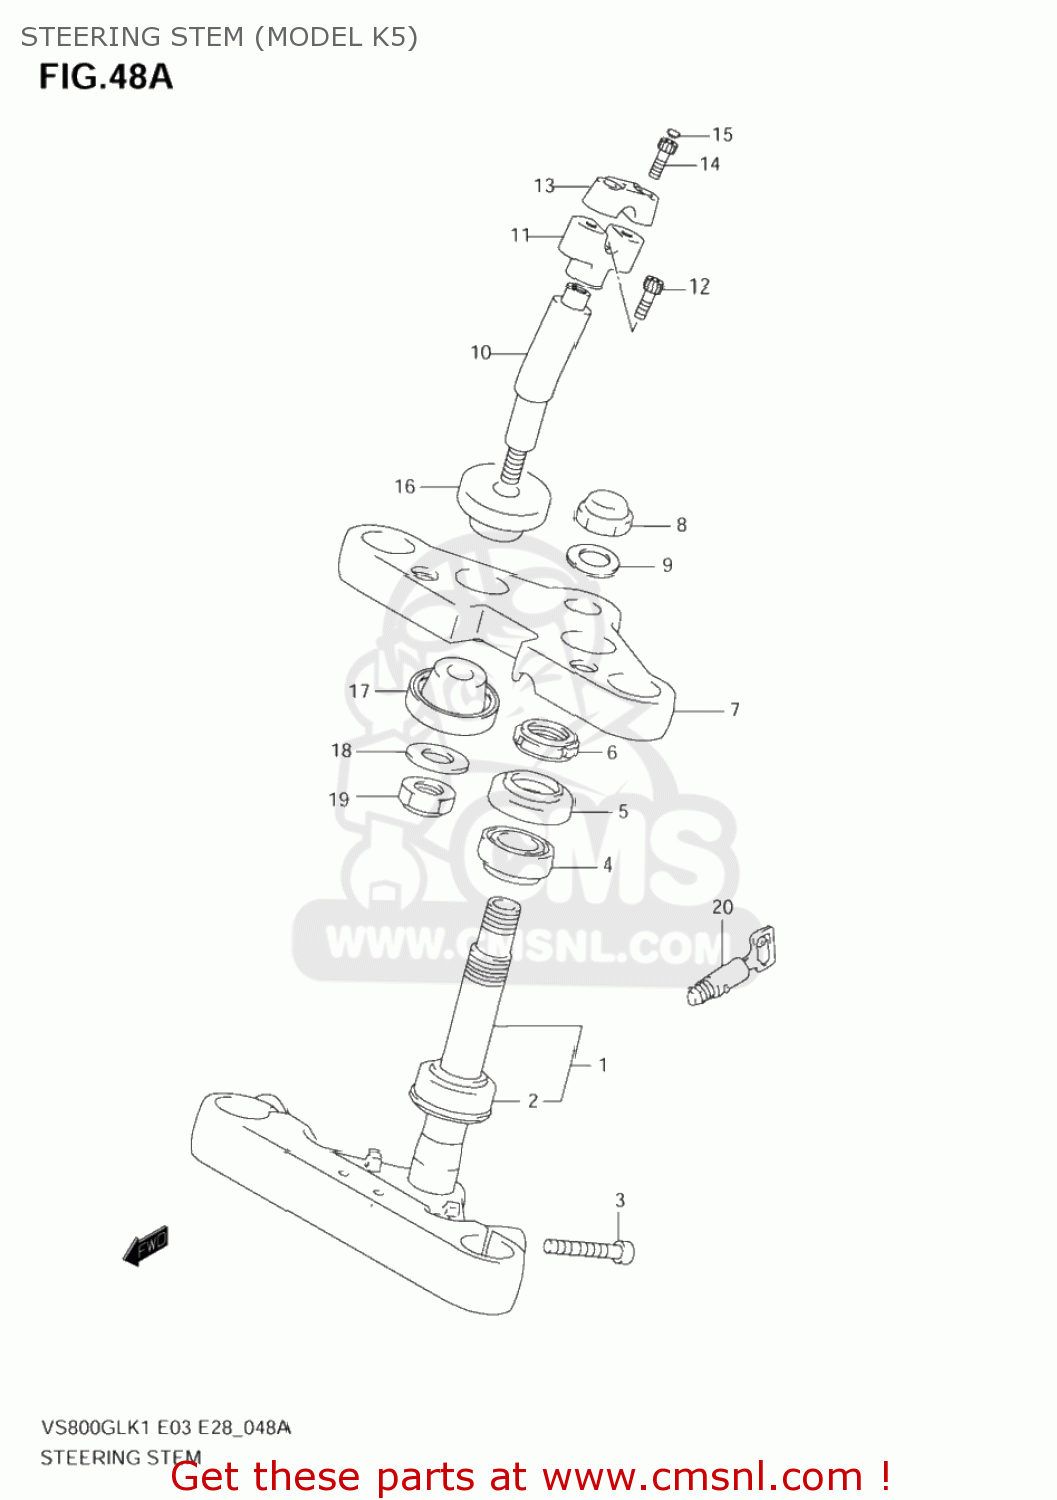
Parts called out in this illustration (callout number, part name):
1	STEM,STEERING
2	BEARING(30X55X17)
3	BOLT
4	BEARING(25X47X15)
5	SEAL,STEERING UPR DUST
6	NUT,STEERING STEM(25X44X10)
7	BRACKET,UPR
8	NUT,CAP
9	WASHER(22.5X32X1.6)
10	STAY,HANDLE
11	HOLDER,HANDLE LWR
12	BOLT
13	HOLDER,HANDLE UPR
14	BOLT
15	CAP(OD:14.5)
16	DAMPER,RUBBER
17	CUSHION,RUBBER UNDER
18	WASHER
19	NUT
20	LOCK SET,STEERING
